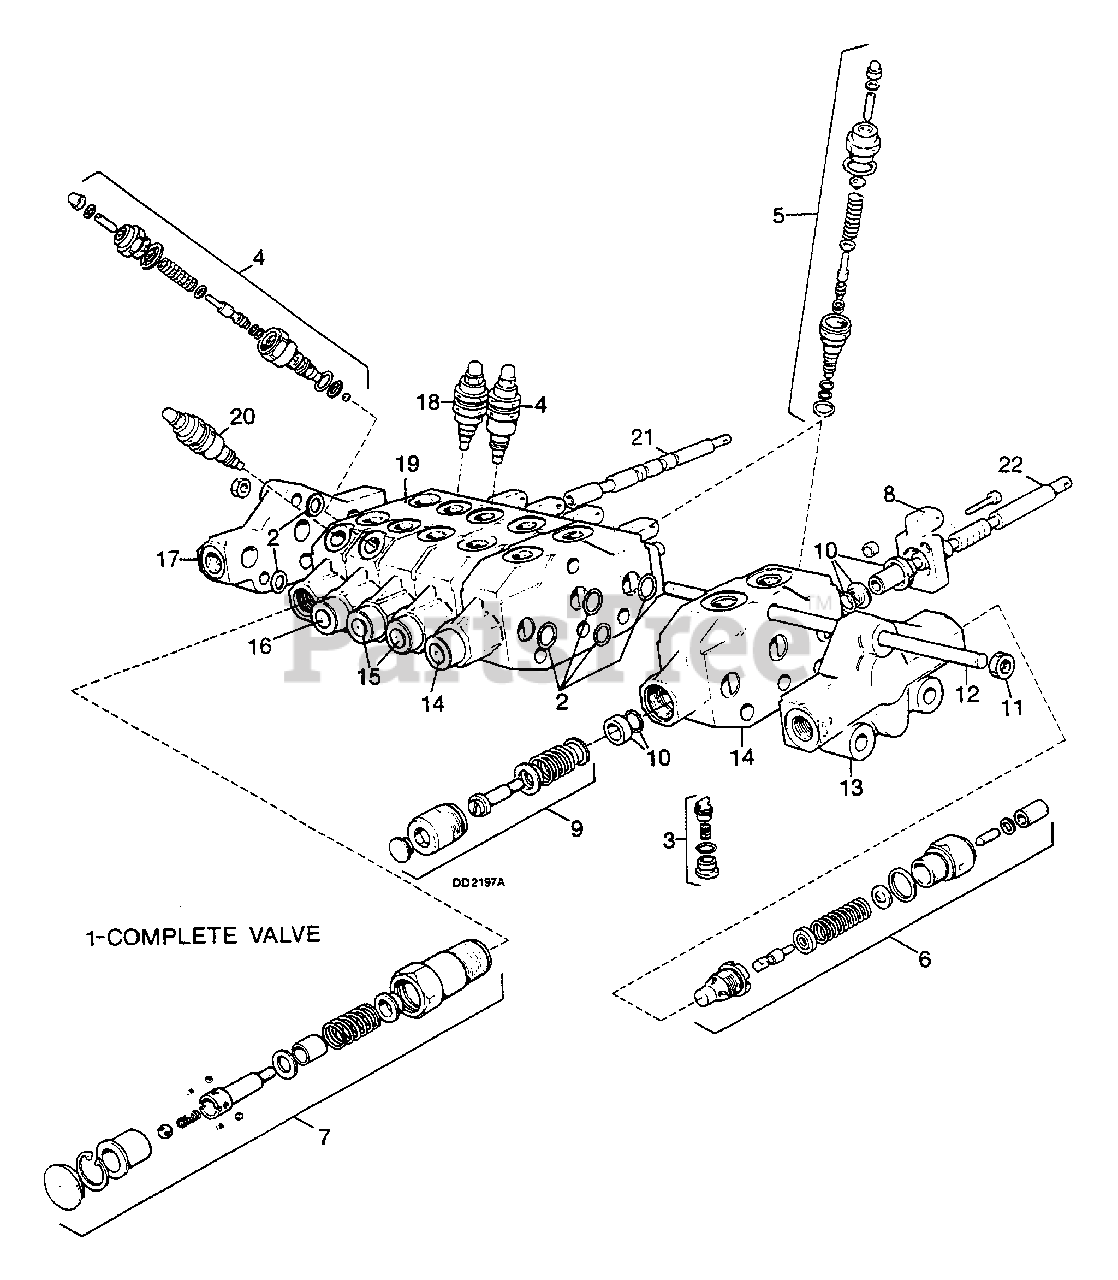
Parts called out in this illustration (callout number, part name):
1	Console valve
2	Section seal repair kit
3	Check valve assembly
4	Shock/dampening valve, 2000 psi
5	Shock/dampening valve, 2500 psi
6	Relief valve assembly
7	Spool position control asy
8	Lever bracket
9	Spool position control asy
10	Spool repair kit
11	8mm x 1.25mm Pitch hex nut
12	M8 x 1.25 x 276 Tie rod
13	Front port inlet section compl.
14	Dipperstick & bucket segments complete
15	Stabilizer segment complete
16	Swing segment complete
17	Standard exhaust section
18	Shock/dampening valve, 3500 psi
19	Boom segment complete
20	Shock/dampening valve, 2500 psi
21	Spool
22	Spool
